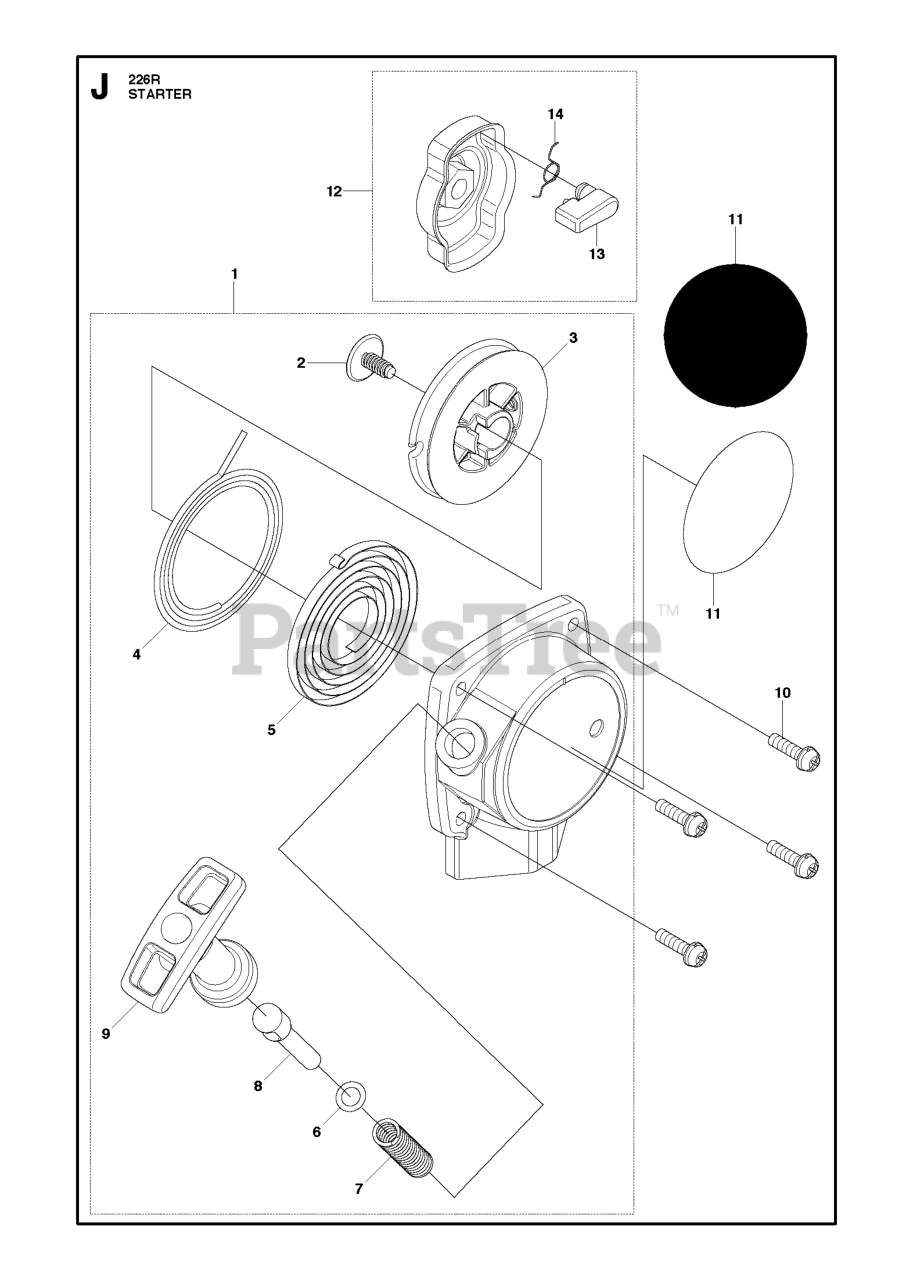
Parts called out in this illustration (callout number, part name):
2	SCREW
5	SPRING, SPIRAL
8	COLLAR (RPLS T160075320)
